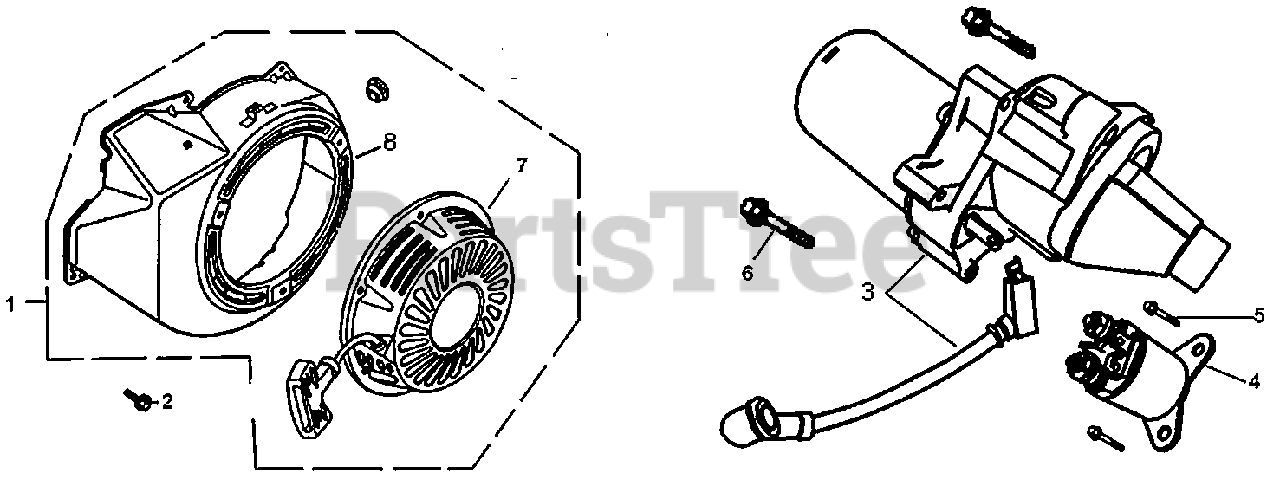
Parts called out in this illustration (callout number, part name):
1	STARTER ASSY.
2	BOLT, FLANGE, M6X12
3	STARTER MOTOR
4	CONTACTOR ASSY.
5	BOLT-WASHER, M6X14
6	BOLT, FLANGE,M8X35
7	ASSY, RECOIL STARTER
8	BLOWER HOUSING, RECOIL STARTER
